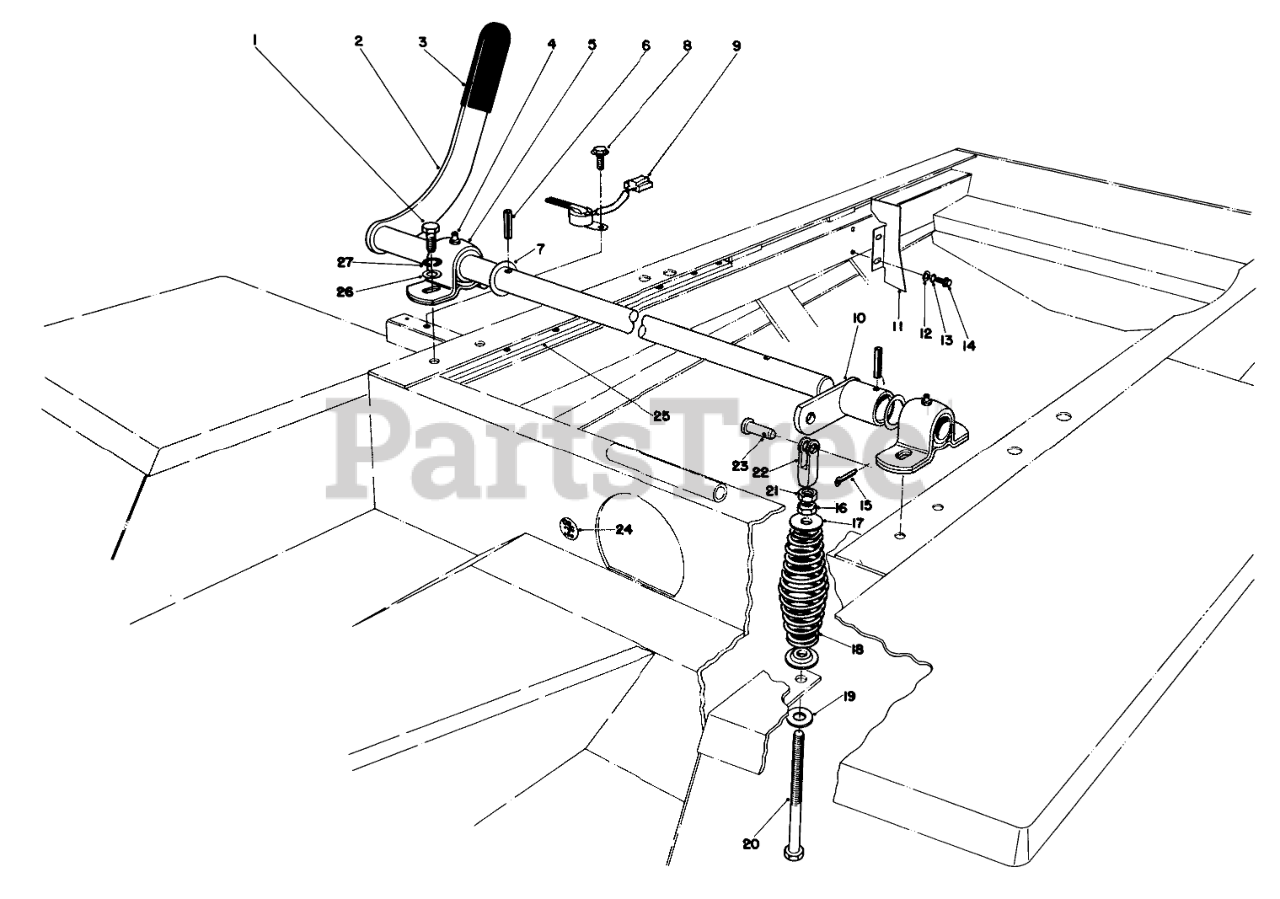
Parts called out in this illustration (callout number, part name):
1	Bolt
2	P.T.0. Lever
3	GRIP-HANDLE
4	FITTING-GREASE
5	BEARING
6	PIN-SPRING
7	THRUST WASHER
8	SCREW-THD FRM,HWH
9	SWITCH ARM
10	Engagement Arm
11	Shield-Heat
12	WASHER-PLAIN
13	WASHER-LOCK
14	SCREW-HWHTF
15	PIN-COTTER
16	NUT-HEX
17	SPRING RET TOP
18	COMP SPRING
19	WASHER
20	SCREW-ADJUSTING
21	NUT-HJ
22	Yoke
23	PIN-CLEVIS
24	OIL DECAL
25	Bar Frame Rail
26	WASHER-FLAT
27	WASHER-LOCK
